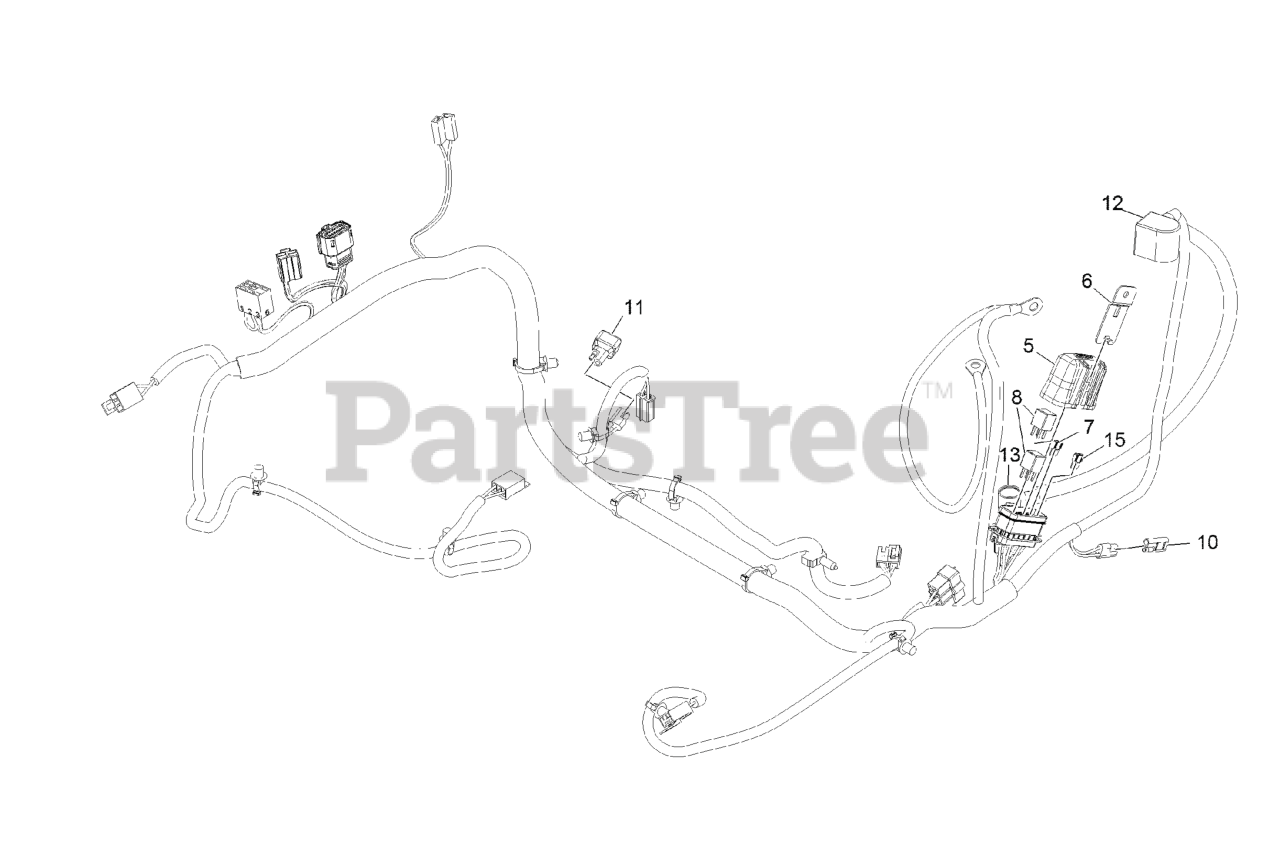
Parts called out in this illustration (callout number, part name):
5	COVER-BLOCK, FUSE
6	CLIP-MOUNTING
7	FUSE-MINI BLADE, 20 AMP
8	RELAY-MICRO
10	CAP-PLUG
12	INSULATOR-BATTERY
13	INSULATOR-SOLENOID
15	FUSE-MINI BLADE, 15 AMP
